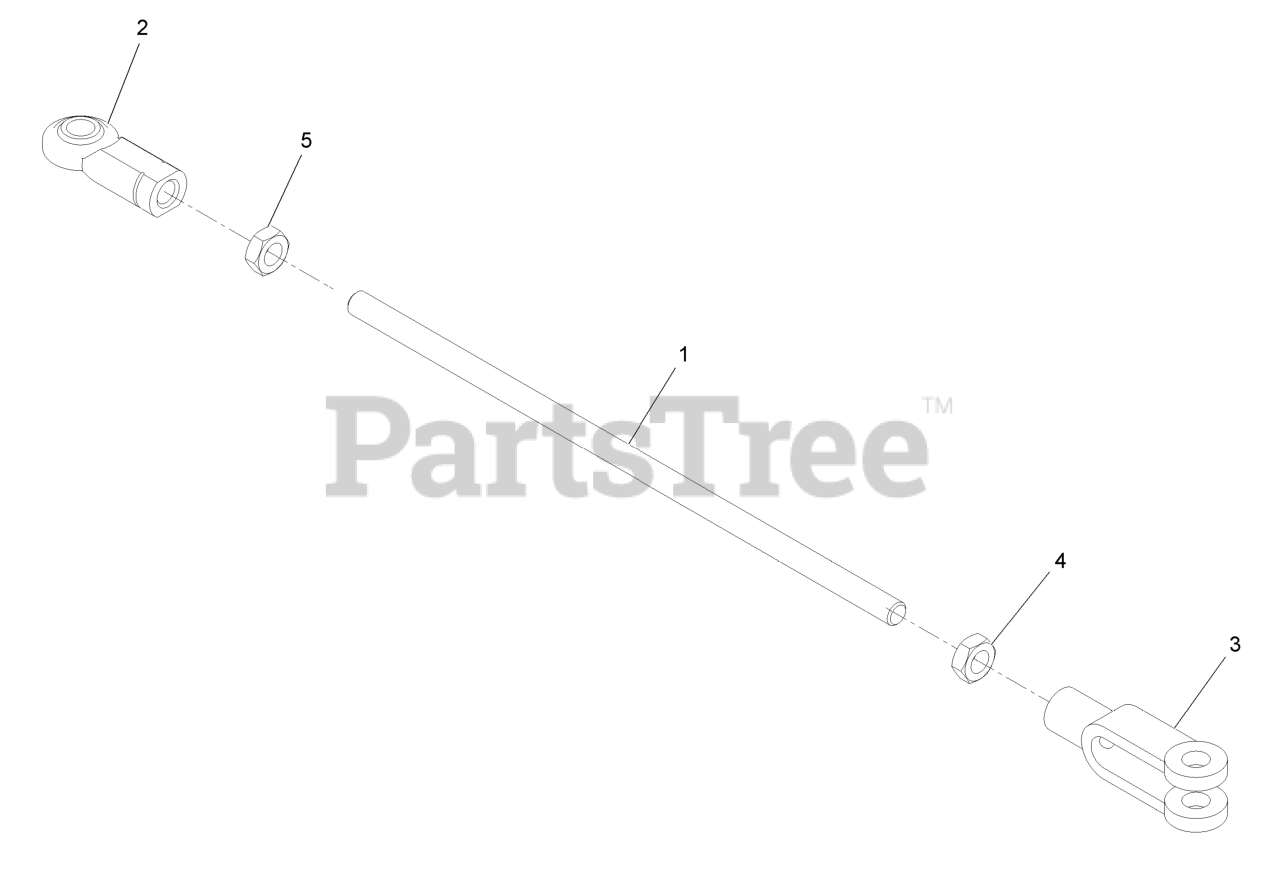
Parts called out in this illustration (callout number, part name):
1	ROD-BRAKE LINKAGE
2	JOINT-BALL END, LH
3	YOKE-LINKAGE, BRAKE
4	NUT-HJ
5	NUT-HEX JAM, LH
